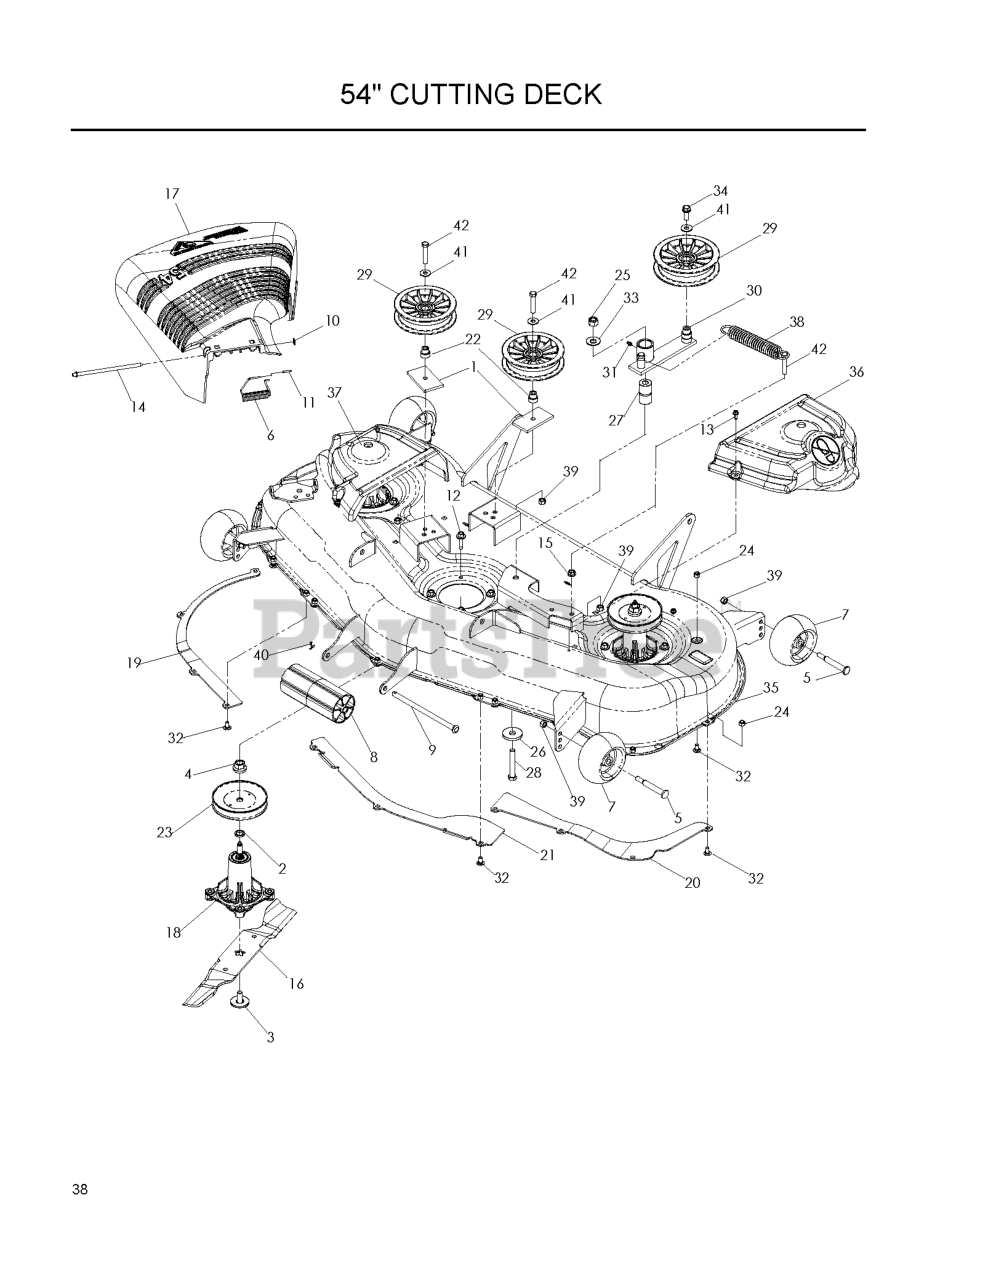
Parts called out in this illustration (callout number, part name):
1	SUPPORT PLATE
2	WASHER-SPACER
3	BOLT 7/16 ASM BLADE
4	LOCKNUT - 9/16
5	BOLT, SHOULDER
6	TORSION SPRING
7	WHEEL GAGE DONUT
8	NOSE ROLLER 48"
9	NOSE ROLLER ROD
10	PUSH NUT
11	CAP-SLEEVE
12	WASHER HEAD SCREW
13	SCREW- 1/4-20 X 5/8
14	ROD.HINGE
15	NUT 3/8C WHIZ
16	BLADE STANDARD 54
17	DEFLECTOR, 54"
18	MANDREL GREASABLE
19	BAFFLE, RIGHT 54"
20	BAFFLE LEFT 54
21	BAFFLE, CENTER, 54"
22	IDLER BUSHING
23	PULLEY
24	NUT 5/16 NYLOC
25	NUT 1/2-13 HEX NYLOC ZD
26	WASHER, SUPPORT
27	PIVOT BUSHING
28	HCS 1/2C X 3 1/4
29	PULLEY - IDLER, NYLON
31	ZERK
32	CARRIAGE BOLT 5/16C X 5/8"
33	WASHER 1/2 FLAT
34	4CS 3/8C X 1 SERRATED HEAD
35	DECK W/DECALS 54" HUS ORANGE
36	BELT SHIELD, LT
37	BELT SHIELD, RT
39	NUT 3/8-16 NYLOC
40	RP_COTTER PIN 1/8 X 3/4
41	WASHER 3/8 FLAT
42	HCS 3/8C X 2
